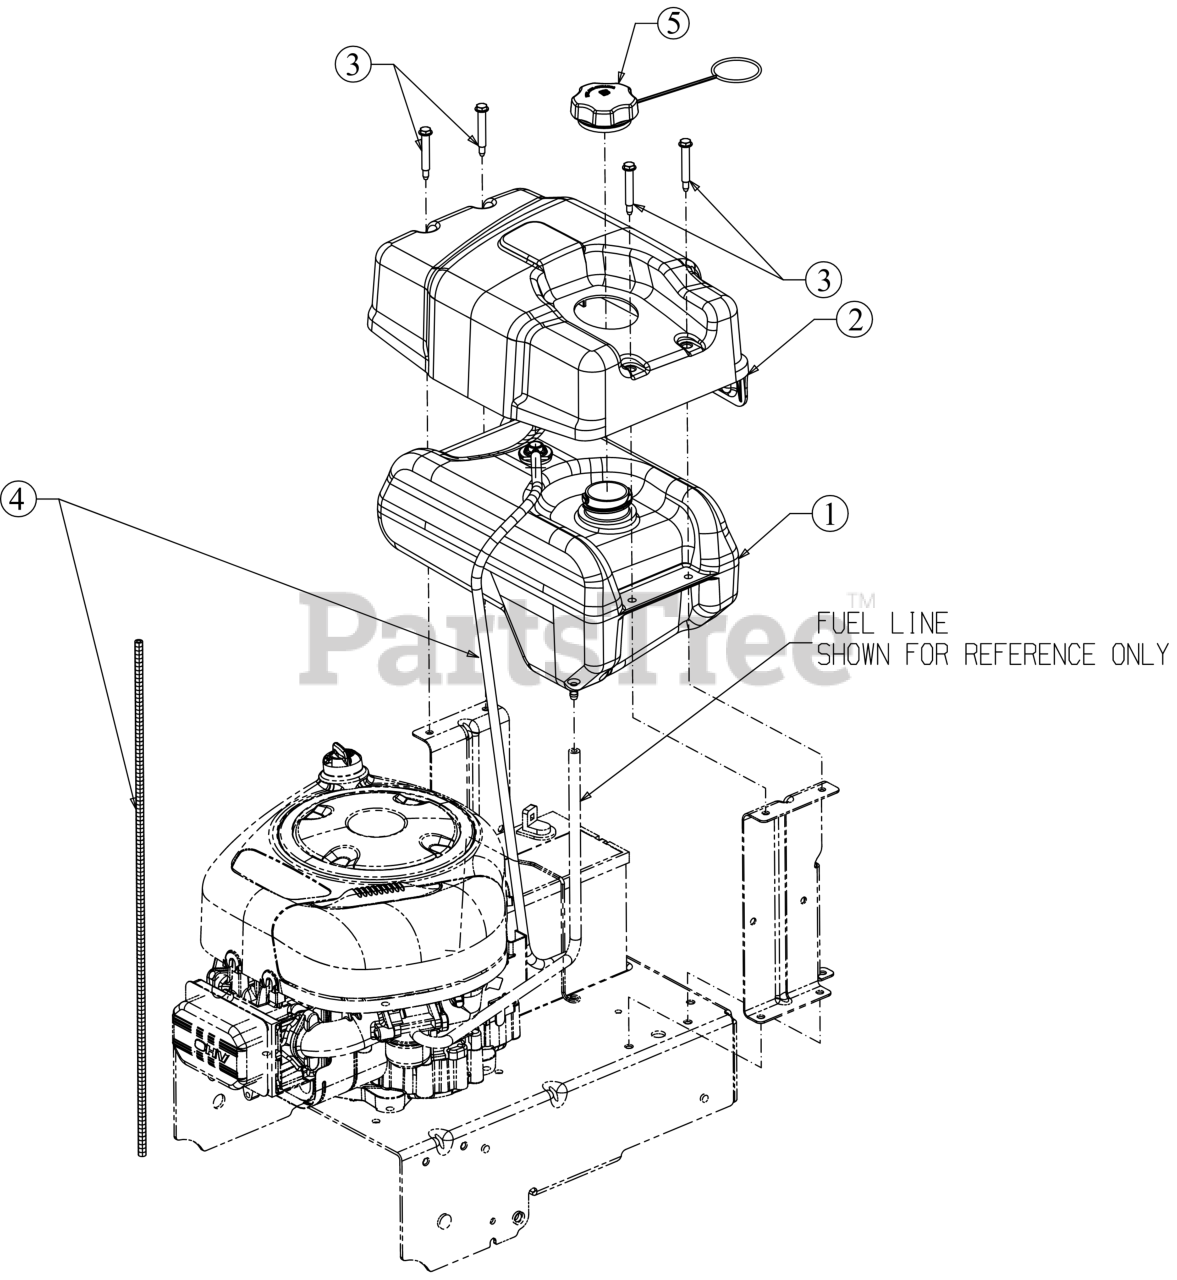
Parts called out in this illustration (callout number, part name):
1	FUEL TANK ASSEMBLY
1	RUBBER GROMMET 23.0 ID x 35.5 OD
1	ROLLOVER FUEL VALVE
2	TANK COVER
3	SHOULDER BOLT .32X1.8X1/4
4	VENT HOSE 3/16 ID
5	FUEL CAP W/HOOP
